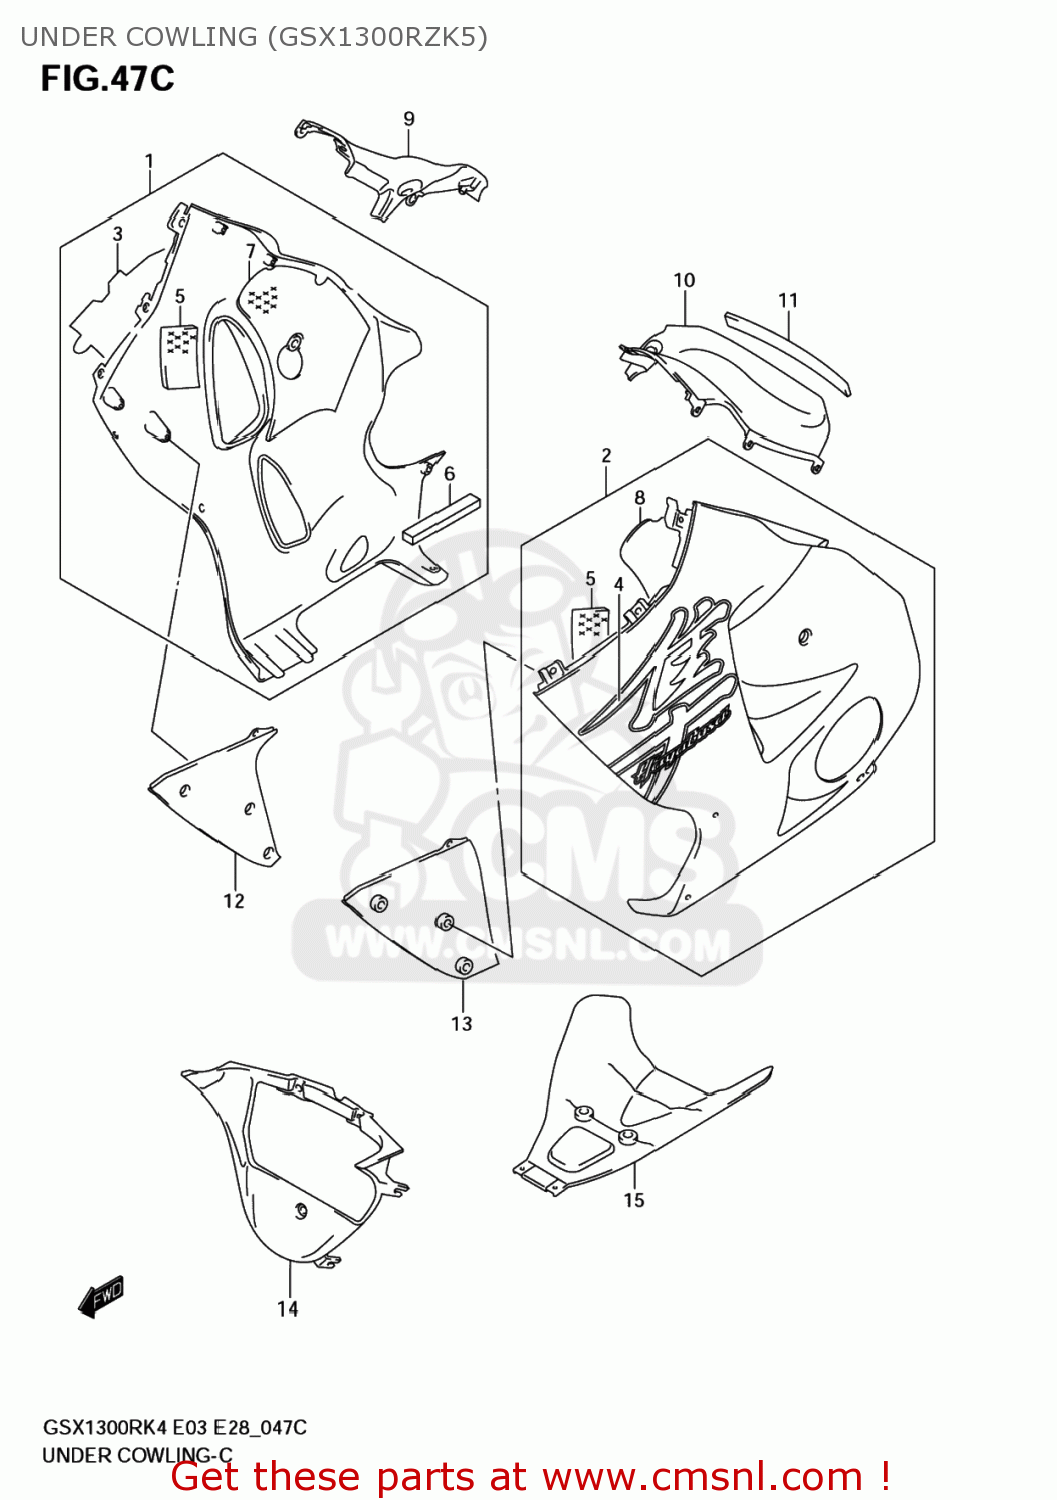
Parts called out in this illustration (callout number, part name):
1	COWL ASSY, UNDER RH (GRAY)
2	COWL ASSY, UNDER LH (GRAY)
3	EMBLEM,COWLING UNDER,R
4	EMBLEM,COWLING UNDER,L
5	CUSHION,UNDER COWLING NO,1
6	CUSHION,ENGINE COVER,RIGHT
7	CUSHION,UNDER COWLING NO.2,R
8	CUSHION,UNDER COWLING,L
9	PANEL,SIDE,R
10	PANEL,SIDE,L
11	MOLDING,SIDE PANEL
12	COWLING,UNDER INNER,R
13	COWLING,UNDER INNER,L
14	COWLING,UNDER CTR
15	COWLING,UNDER RR
